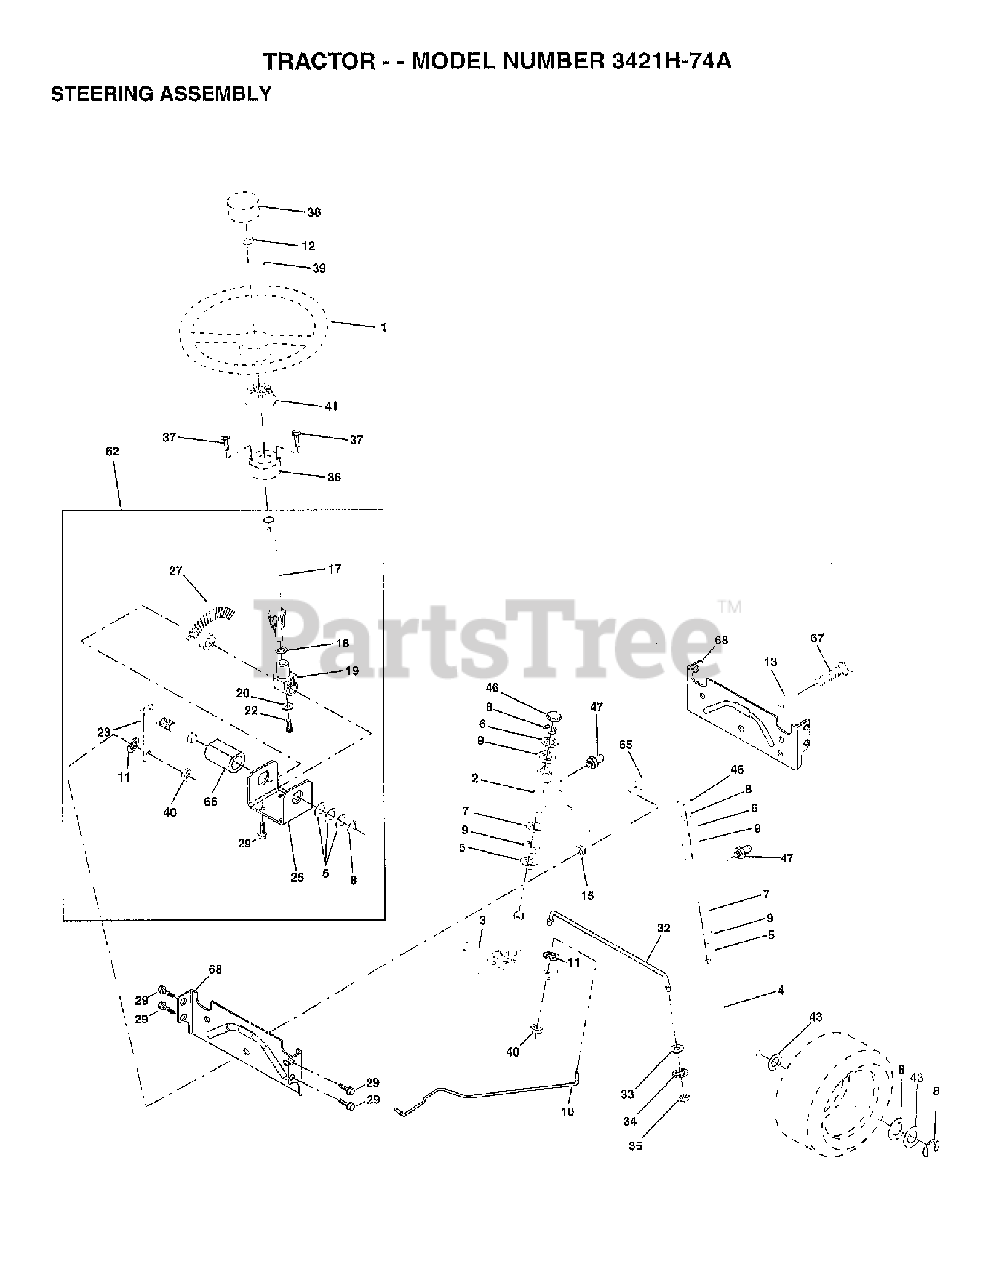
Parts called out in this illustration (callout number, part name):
1	Steering Wheel
2	Half Axle Assembly, Welded
3	SPINDLE.ASM.LH
5	WASHER THRUST
8	RING CLIP
9	BEARING.STEERING.COLUMN
10	DRAGLINK-STAMPED
11	WASHER, LOCK 3/8
12	NUT.HEX.1/2-20
13	BEARING AXLE
15	LOCK NUT
17	STEERING SHAFT
18	THRUST WASHER
19	SHAFT,SUPPORT
20	WASHER
23	SHAFT,PITMAN
25	BRACKET STEERING
27	GEAR.SECTOR
33	WASHER M
34	LOCKWASHER
35	LOCKNUT
37	SCREW.TT.#10-32X.5.3/8.FLANGE
38	INSERT STR WHL
40	NUT
46	CAP.SPINDLE.BLACK
47	ZERK.GREASE.TAPERED
51	NUT.71038.31-18.HEX.NYLOCK
54	BOLT.5/16-18X1-1/4 FULL.THREAD
62	STEERING KIT
65	SPACER AXLE
66	BEARING ARM
67	BOLT.HEX.FINISHED.5/8
68	AXLE, BRACE
